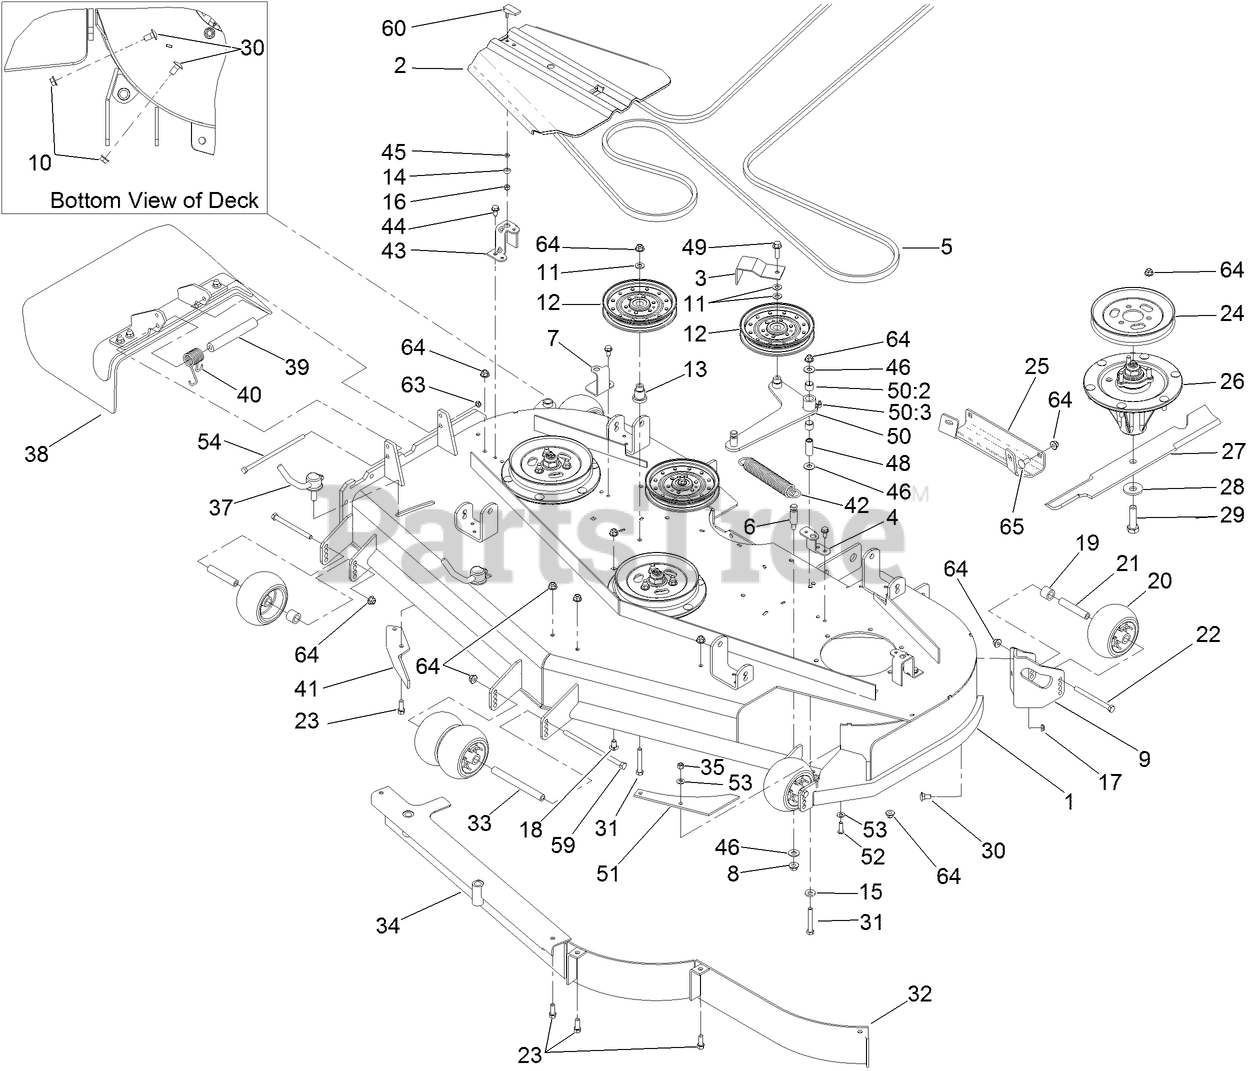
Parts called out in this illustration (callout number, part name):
1	DECK DECAL ASM
2	COVER-BELT
3	GUIDE-BELT
4	BRACKET-COVER, TALL
5	BELT-V
6	PIN-THREADED, SPRING ANCHOR
7	BRACKET-COVER
8	NUT-HF
9	MOUNT-WHEEL, LH
10	NUT-HHF, WHIZ
11	WASHER-FLAT
12	IDLER-PULLEY, FLAT
13	MOUNT-PULLEY
14	BUSHING-LATCH, SWELL
15	WASHER-BELLEVILLE
16	NUT-LOCK, HH
17	NUT-LOCK, NI
18	SCREW-CARR
19	TUBE-SPACER
20	ROLLER-SCALP, ANTI
21	TUBE-SPANNER
22	SCREW-HH
23	SCREW-HWH
24	Pulley
25	Plate-Skid
26	SPINDLE ASM
27	BLADE-HI FLOW
28	Washer-Blade Bolt, Heavy
29	SCREW-BLADE
30	SCREW-CARR
31	SCREW-HH
33	SPACER-WHEEL
35	NUT-LOCK, NI
37	LEVER ASM
38	RUBBER DEFLECTOR ASM
39	SPACER
40	SPRING-TORSION
41	BAFFLE-DISCHARGE
42	SPRING-EXTENSION
43	BRACKET-COVER
44	SCREW-HWHTF
45	WASHER
46	WASHER-FLAT
48	BUSHING
49	SCREW-HHF
50	DECK IDLER ARM ASM
50:2	SLEEVE-BEARING
50:3	FITTING-GREASE, 90 DEG
51	PLATE-TURBO
52	SCREW-HSBH
53	WASHER-SPRING
54	SCREW-HH
59	SCREW-HH
60	HANDLE-LATCH, SWELL
63	NUT-LOCK, NI
64	NUT-HF, NI
65	SCREW-CARR
